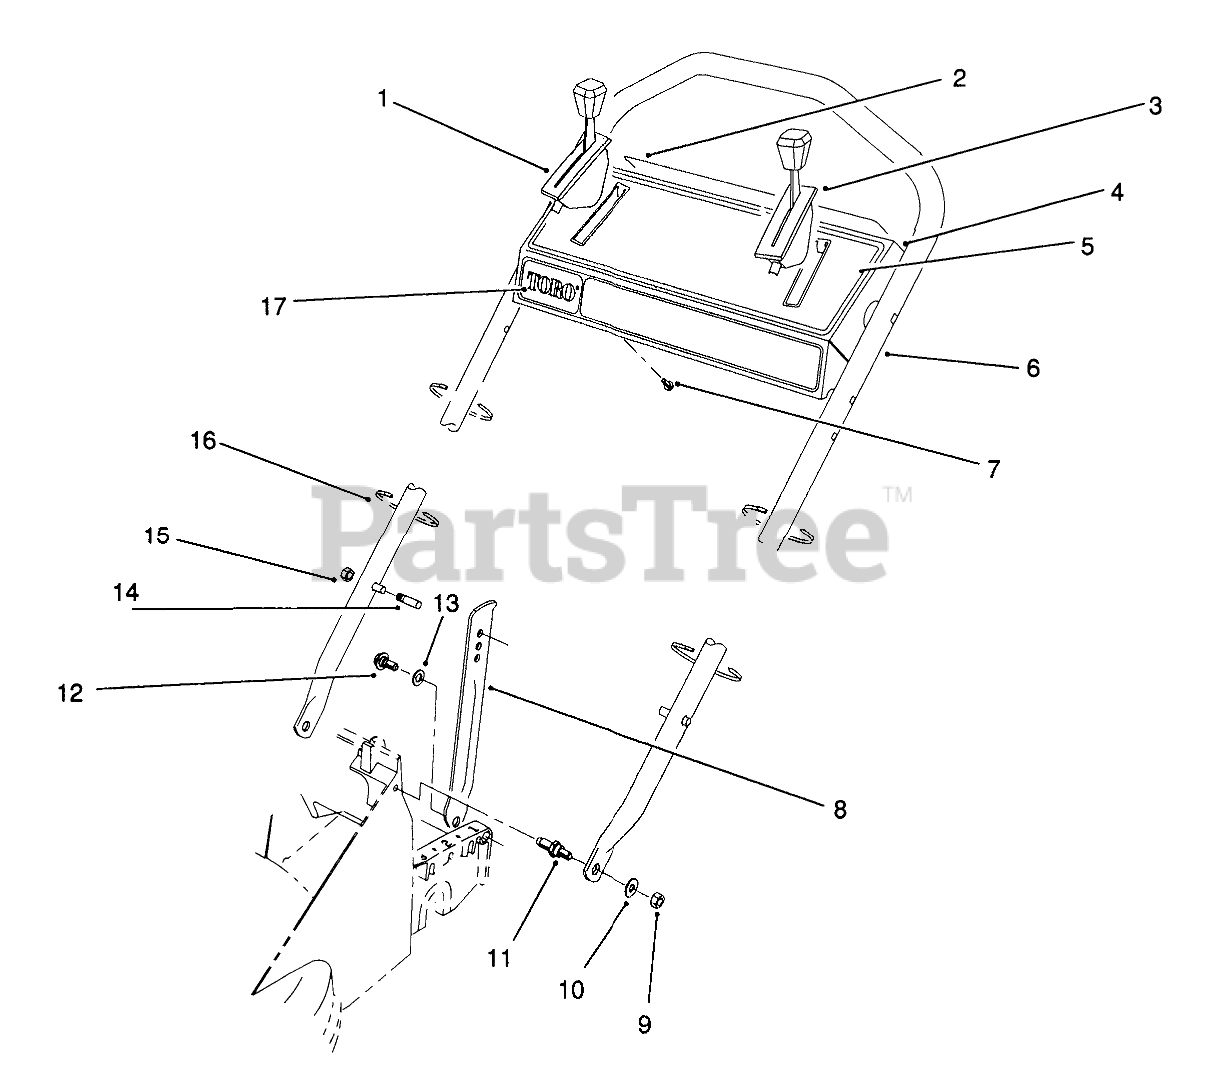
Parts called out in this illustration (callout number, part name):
1	Control-Ground Speed
2	DECAL - PANEL, REAR
3	THROTTLE CONTROL
4	Control Panel Assembly 65-5060 (Incl. Ref. #2 & 5 )
5	DECAL - INSTRUCTION
6	HANDLE
7	SCREW-HWHTF
8	HANDLE LATCH
9	NUT-LOCK, NI
10	WASHER-PLAIN
11	SCREW - SHOULDER STUD
12	SCREW-SHOULDER
13	NYLON WASHER
14	HANDLE PIN
15	NUT-LOCK, NI
16	TIE-CABLE
17	DECAL - TORO PANEL
